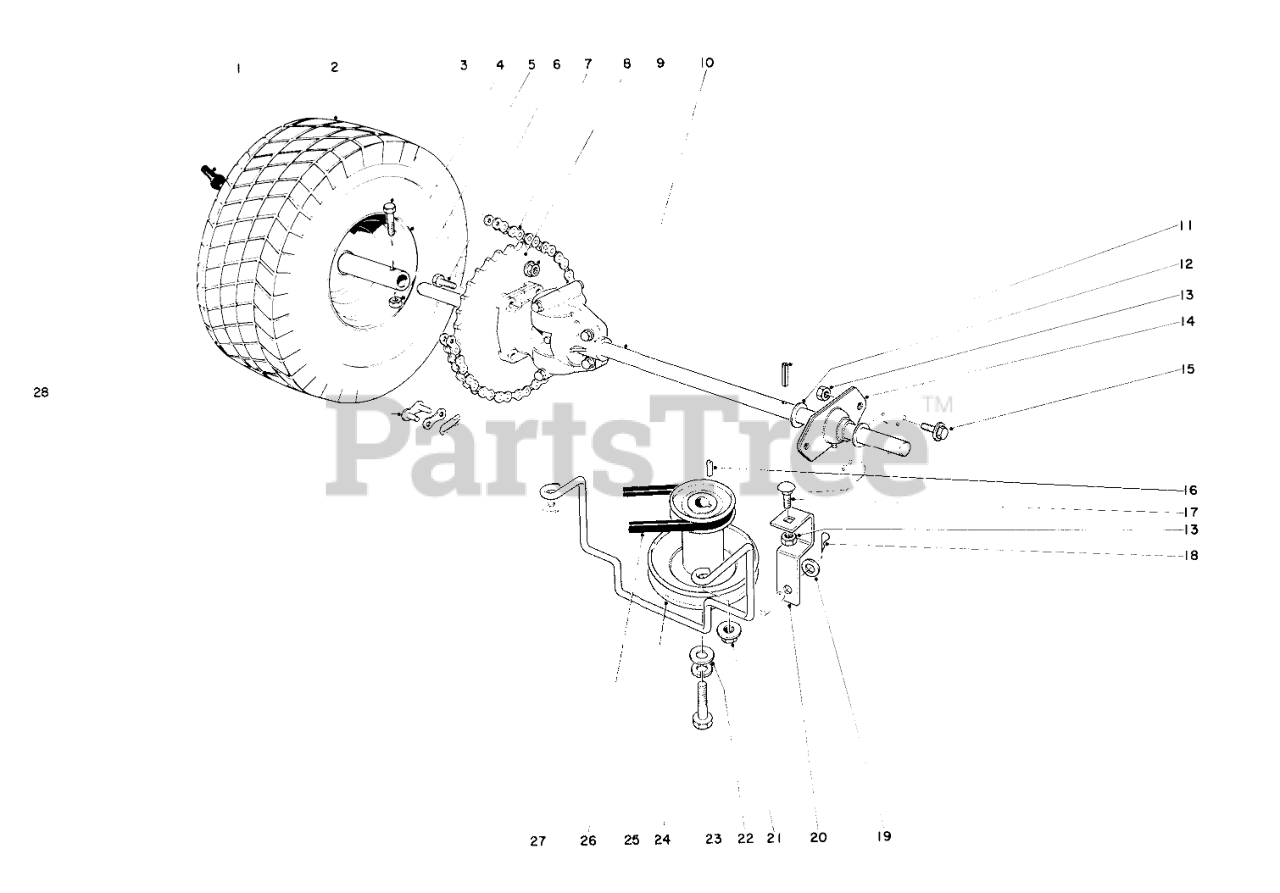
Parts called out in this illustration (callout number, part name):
1	STEM-VALVE
2	Tire
3	SCREW-HH
5	NUT-LOCK, SIDE
6	SCREW-HH
7	Roller Chain
8	Sprocket
9	NUT-HF
10	Differential
11	PIN-ROLL, SLOTTED
12	WASHER
13	Nut
14	Rear Axle Bearing
15	SCREW-HHF
16	KEY-SQUARE
17	SCREW-CARR
18	PIN-COTTER
19	WASHER-PLAIN
20	Bracket
21	NUT-HF
22	WASHER-FLAT
23	SCREW-HH
24	WASHER-LOCK
25	Pulley
26	V-Belt
27	Belt Retainer
28	LINK-CONNECTING
